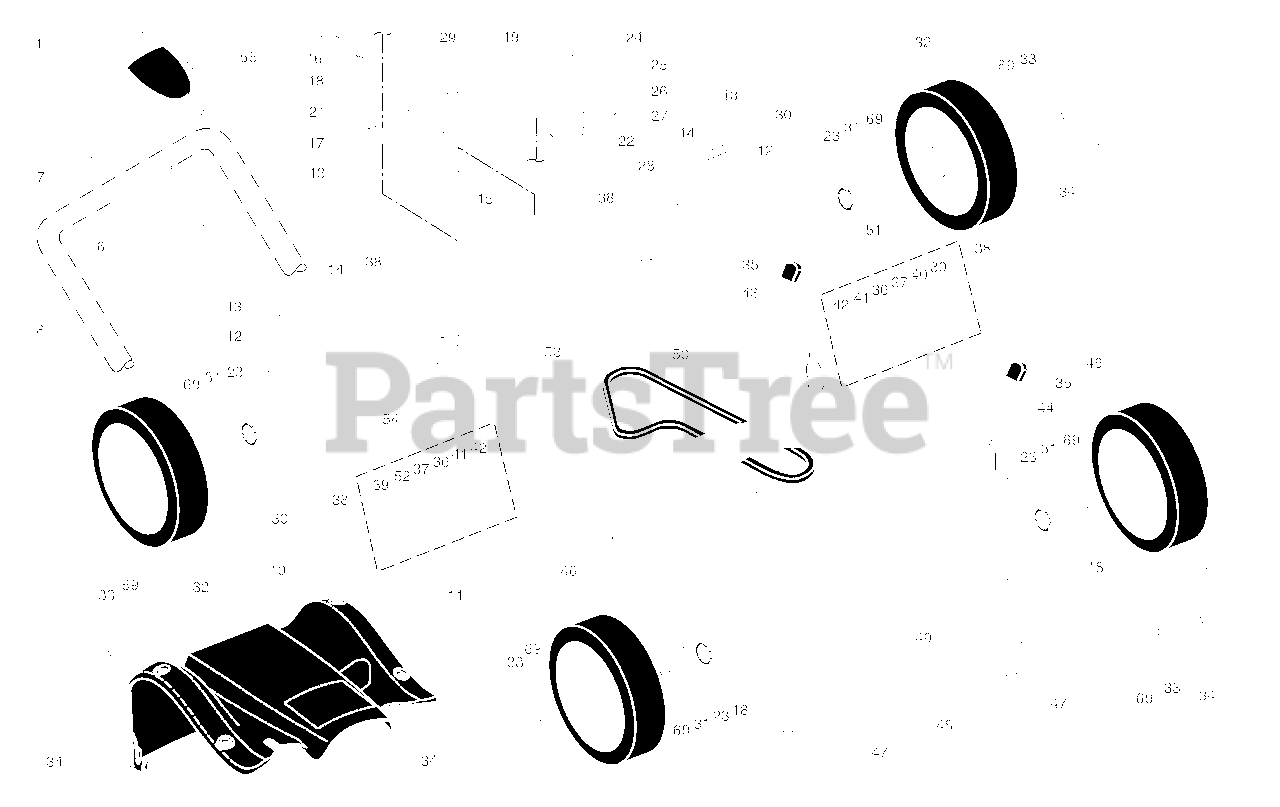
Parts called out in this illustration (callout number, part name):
1	Drive Control Assembly, Complete
6	Screw, Torx Head #8-5/8
7	Bracket, Mounting, Drive Control
8	Cap, Drive Control, Bottom
10	Cover Assembly, Drive
12	Ring, Retaining
14	Bearing / Axle Support
15	Gear Case Assembly
16	Spring, Return
17	Bracket, Gear Case / Drive Pulley
19	Pulley, Drive
21	Nut, Hex
22	Pulley Assembly, V-Groove
23	O-Ring
24	Nut, Hex, Flangelock
25	Nut, Hex, Lock
26	Idler Arm
27	Pulley, Idler
28	Bolt, Hex Head, Shoulder
29	Screw 1/4-20 x 1/16
30	Cover, Dust, Wheel
31	Washer, Flat 3/8
32	Wheel Assembly, Rear 9 x 2-1/4
33	Nut, Hex
34	Hubcap
36	Spring, Torsion
40	Retainer, Drive, LH
41	Disc, Drive
42	Seal, Friction
43	Lever, Selector, Wheel Height, Rear
44	Lever, Selector, Wheel Height, Front
46	Wheel Assembly, Front 9 x 2-1/4
47	Bushing, Front Axle
48	Retainer, Hairpin Cotter
49	Torque Shaft Assembly, Front
50	Belt, Drive
51	Pinion Assembly, LH
52	Retainer, Drive, RH
53	Rear Axle Assembly
54	Pinion Assembly, RH
55	Decal, Drive Control
69	Bearing, Ball (Wheel)
